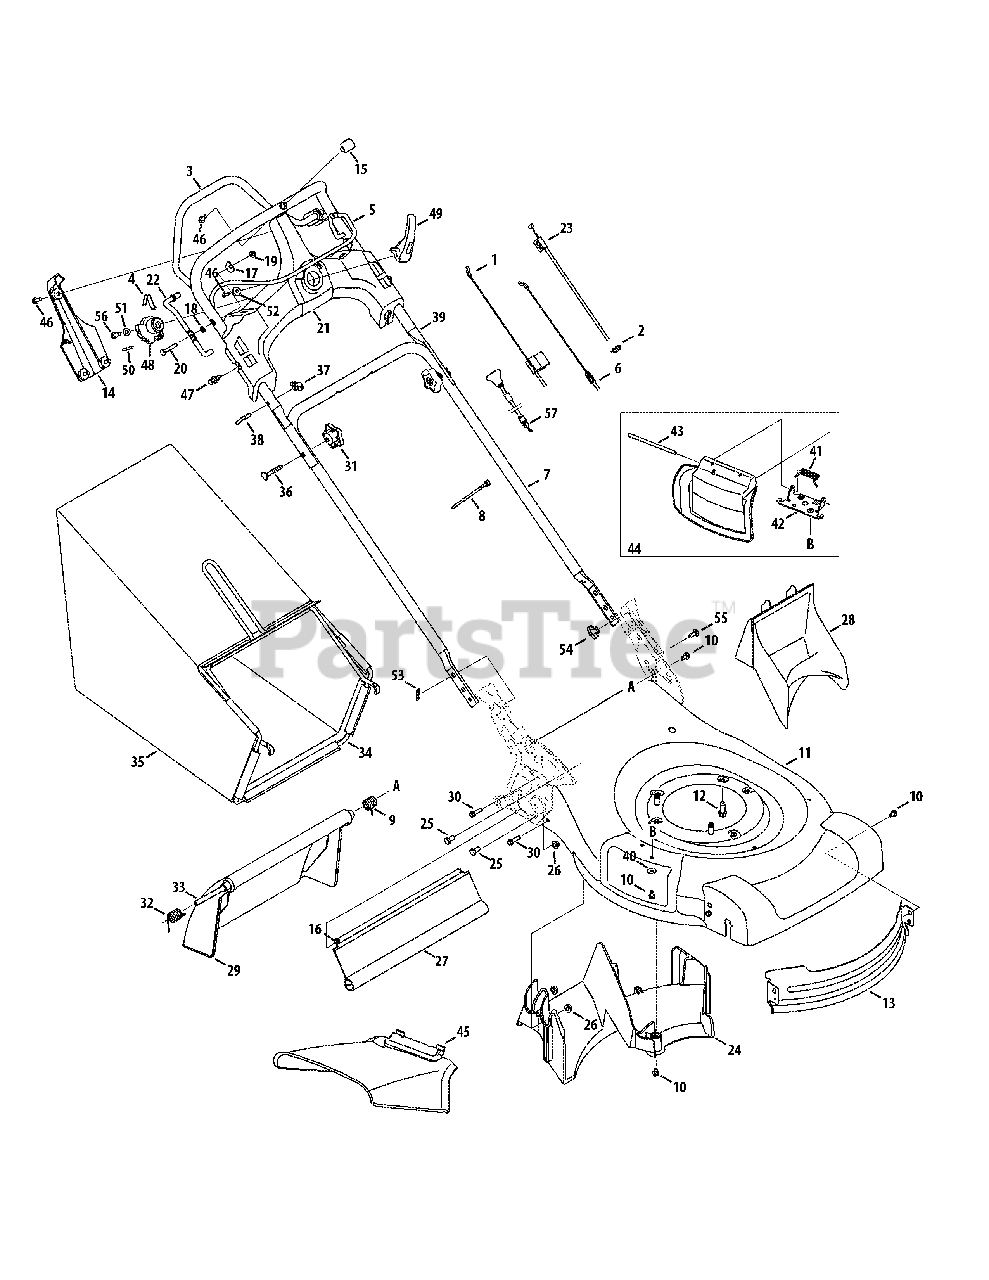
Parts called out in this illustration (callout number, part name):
1	Drive Cable
2	Rubber Grommet
5	Blade Control
6	Control Cable
8	Cable Tie
9	Torsion Spring, LH
10	TT Screw, 1/4-20 x .500
13	Front Deck Bae
14	Variable Speed Cont. Panel Cover
15	Variable Speed Cont. Panel Cover
16	Screw, #10-16 x .500
17	Saddle Washer
18	Washer, Lock, 1/4
19	Nut, Flange Lock, 1/4-20
20	Screw, 1/4-20 x 1.50
21	Variable Speed Control Panel
22	Bail Pivot Rod - RH
22	Bail Pivot Rod - LH
23	Variable Speed Cable
25	Screw, 5/16-18 x .625
26	Flange Lock Nut, 5/16-18
27	Trailshield
28	Mulch Plug
29	Rear Door
30	Screw, 1/4-15 x 1.00
31	Star Knob
32	Torsion Spring, RH
33	Door Pivot Rod
36	Carriage Bolt, 5/16-18 x 2.00
40	Bell Washer, .265 x .75 x .062
41	Torsion Spring
42	Chute Deector Adapter
43	Hinge Pin
44	Mulch Plug Assembly
45	Side Discharge Chute
46	Screw, #12-16 x .75
47	Rivet, Plastic
48	4 Speed Actuator
49	Speed Selector Level
51	Washer, Flat, .344 x .688 x .065
52	Washer, Flat, .250 x .750 x .119
53	Cotter Pin
54	Wing Nut
55	Carriage Bolt, 1/4-20
56	Screw, 1/4-15 x .750
57	Choke Cable
